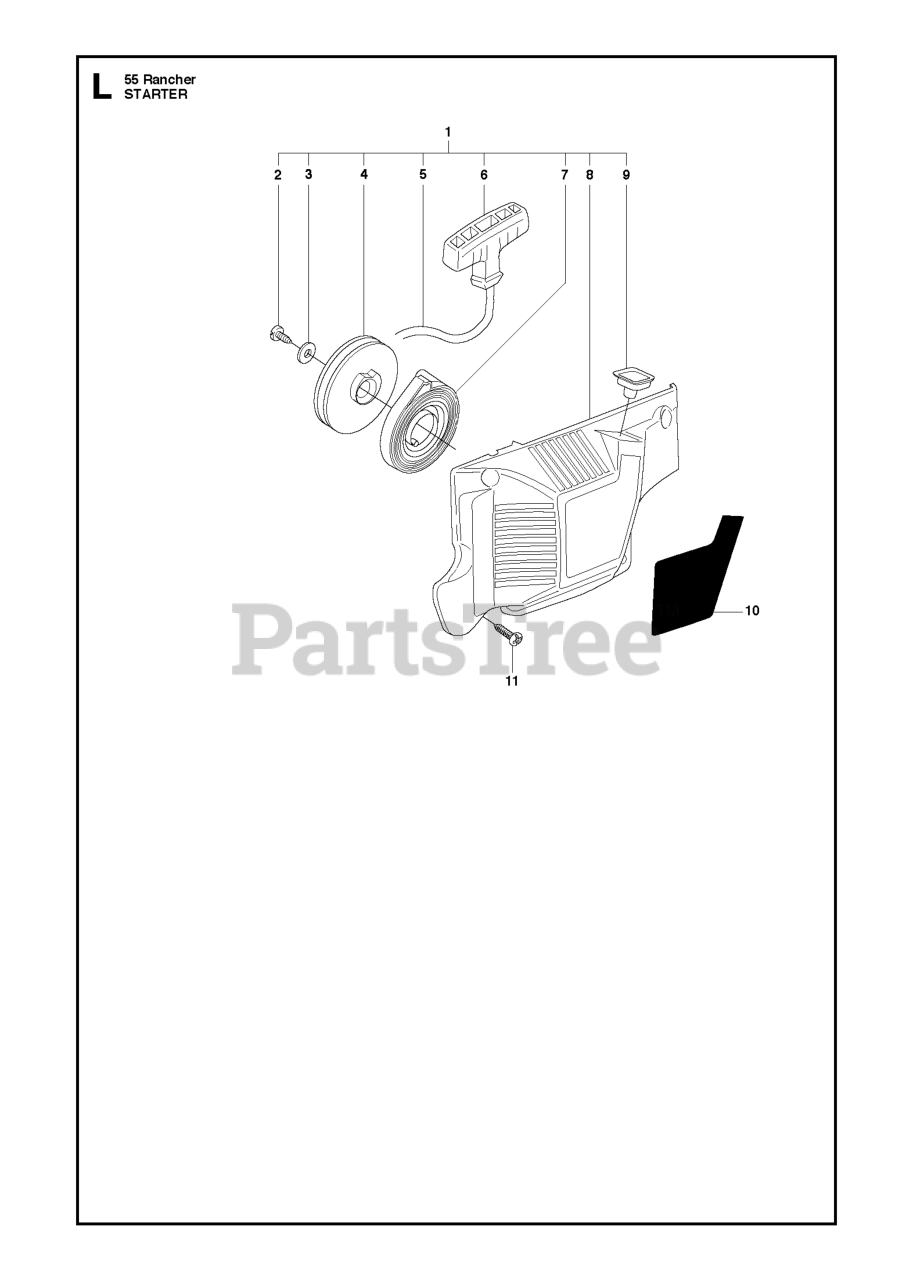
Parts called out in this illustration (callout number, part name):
1	STARTER ASS'Y
2	SCREW
3	WASHER 5.3X15
4	STARTER PULLEY
5	STARTER ROPE
6	STARTER HANDLE
7	RECOIL SPRING
8	STARTER HOUSING
